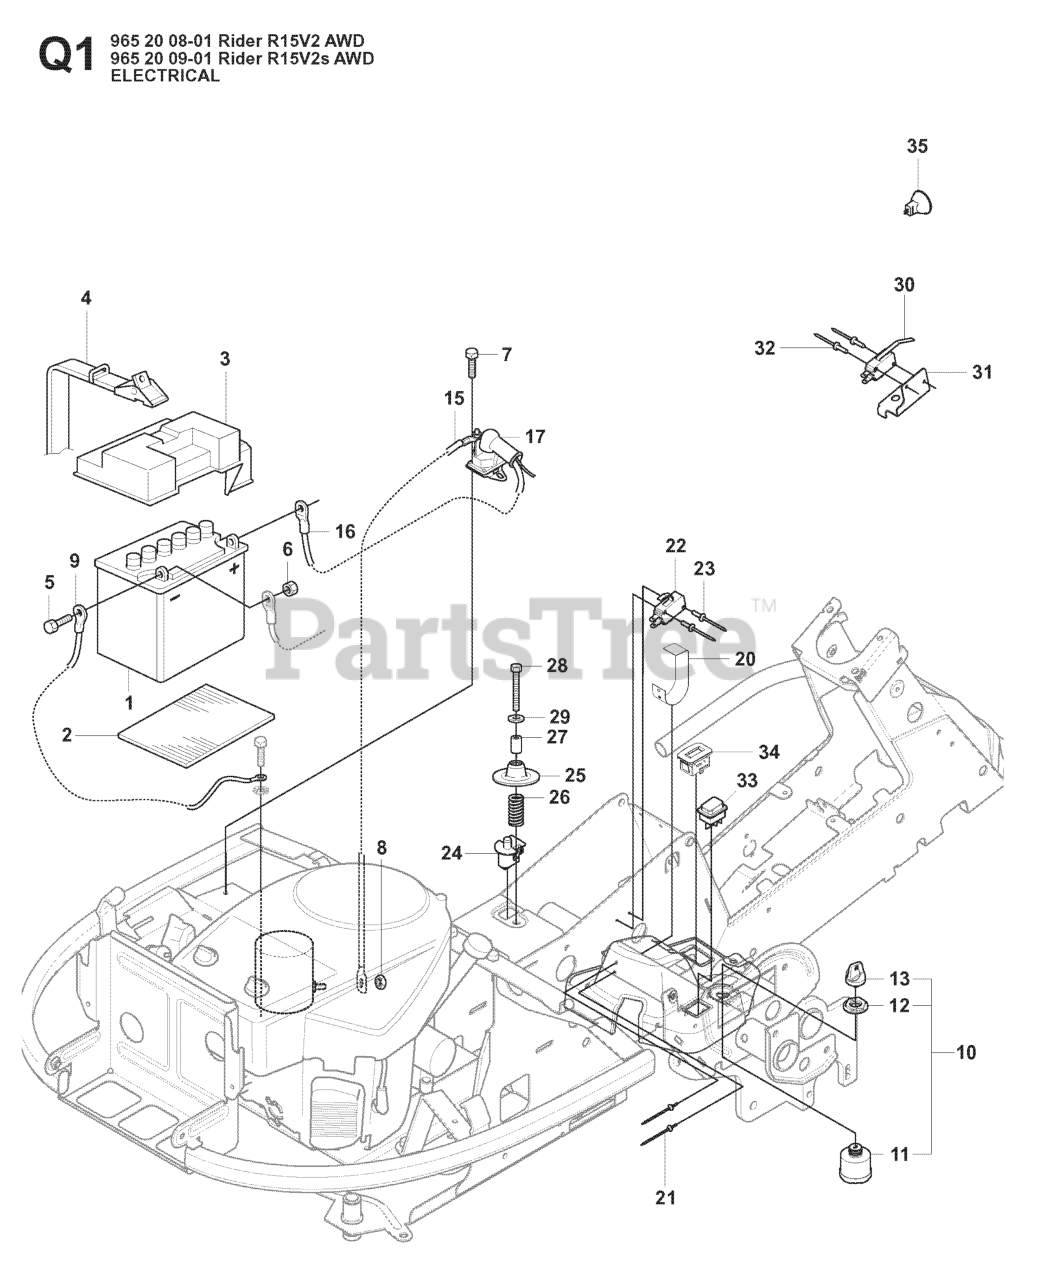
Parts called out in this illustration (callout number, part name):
1	BATTERY - DRY
10	IGNITION SWITCH
11	IGNITION SWITCH
13	IGNITION KEY
22	%BRAKER
27	SPACER TUBE
28	SCREW
29	WASHER BRB 8.4X17
30	RP MICRO SWITCH
